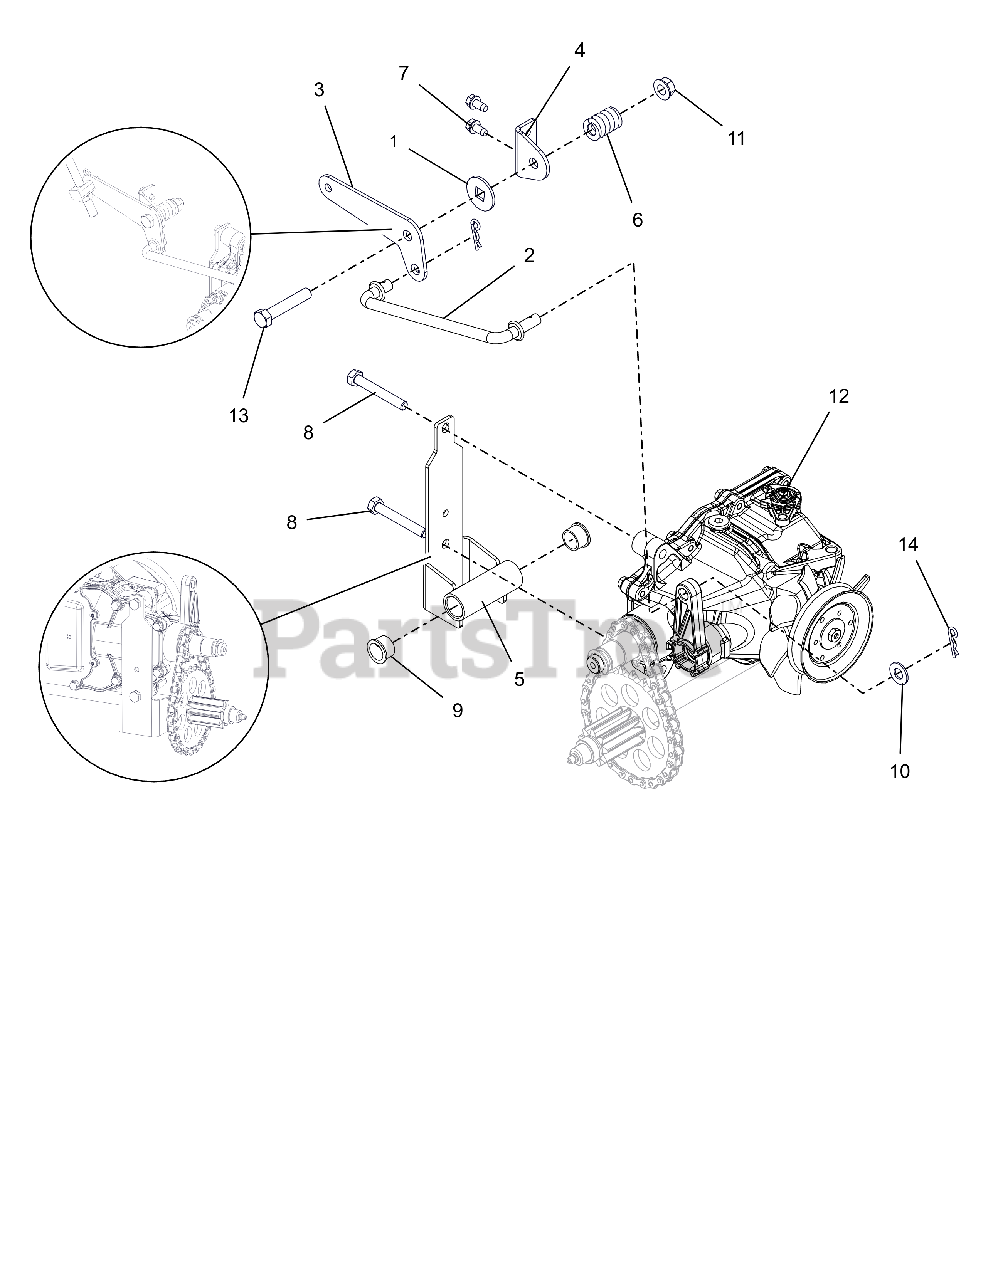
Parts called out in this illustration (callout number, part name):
1	FRICTION WASHER
2	ROD, HYDRO TRANS SHIFT
3	PIVOT, HYDRO TRANS SHIFT
4	BRACKET, HYDRO SHIFT PIVOT
5	TRANS MOUNT, TENSIONING, WHEEL
6	SG-COMP .187X.56X1.62
7	SCR-TAP .25-20X.50 HWH ZCC
8	BLT, HEX .31-18X2.25 G5 ZCC
9	BSHG-FLG .625X.750X.500X.875
10	WSHR,FLT .406X.812X.065 ZCC
11	NUT-LK-TOP-FLG .38-16 ZC120
12	TRANSMISSION, HYDROSTATIC
13	BLT,HEX .38-16X2.00 G5 ZCC
14	PIN, HAIR #213 .08X1.19 ZCC
